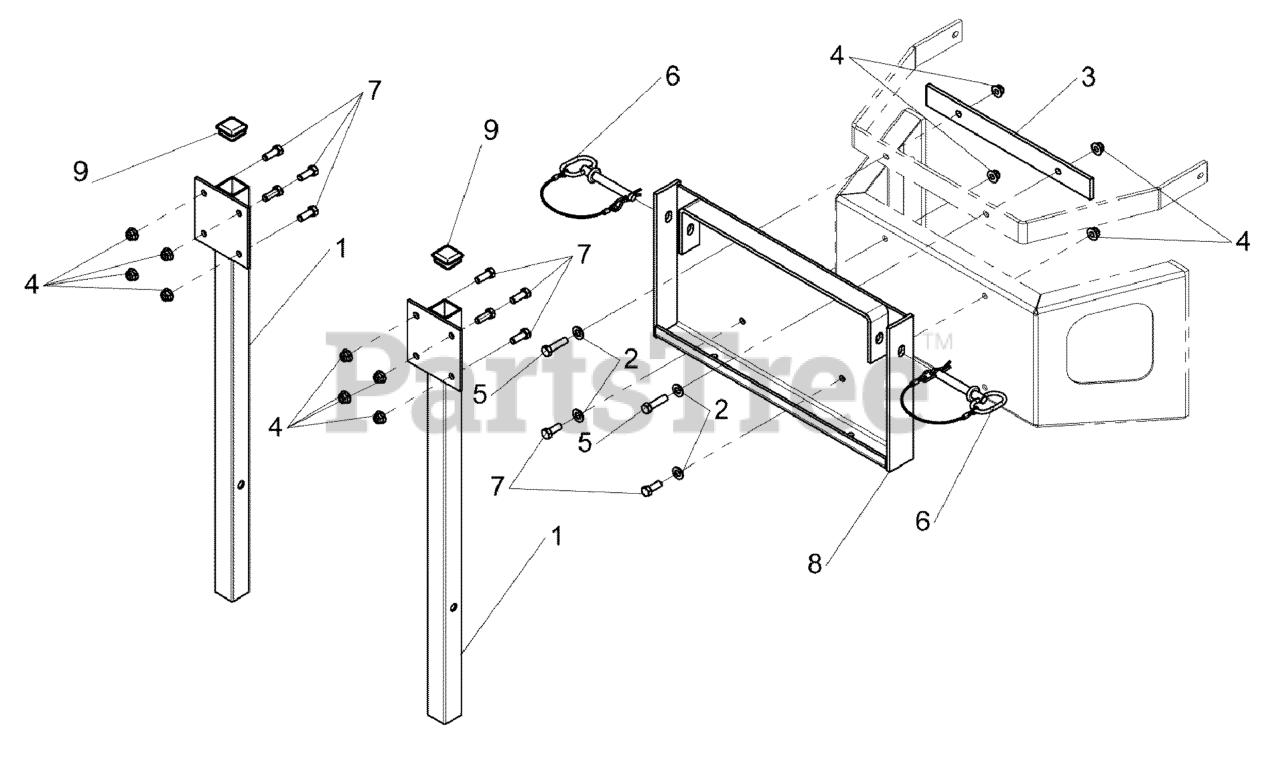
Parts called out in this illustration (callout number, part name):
1	WELD, MOUNT, POST - BLK
2	WASHER, 3/8 SAE
3	BAR, BAGGER SUPPORT, BLACK.
4	NUT, 3/8-16 HEX NYLOCK FLANGE
5	BOLT, 3/8-16 X 1-1/2" GD5 CZ
6	PIN, HITCH, .50 X 3.25 W/ LAY
7	BOLT, 3/8-16 X 1" GD5 CZ
8	WELD, BAGR MNT-1000/IS1000 BLK
9	CAP, PLASTIC, 1-1/2" X 1-1/2
